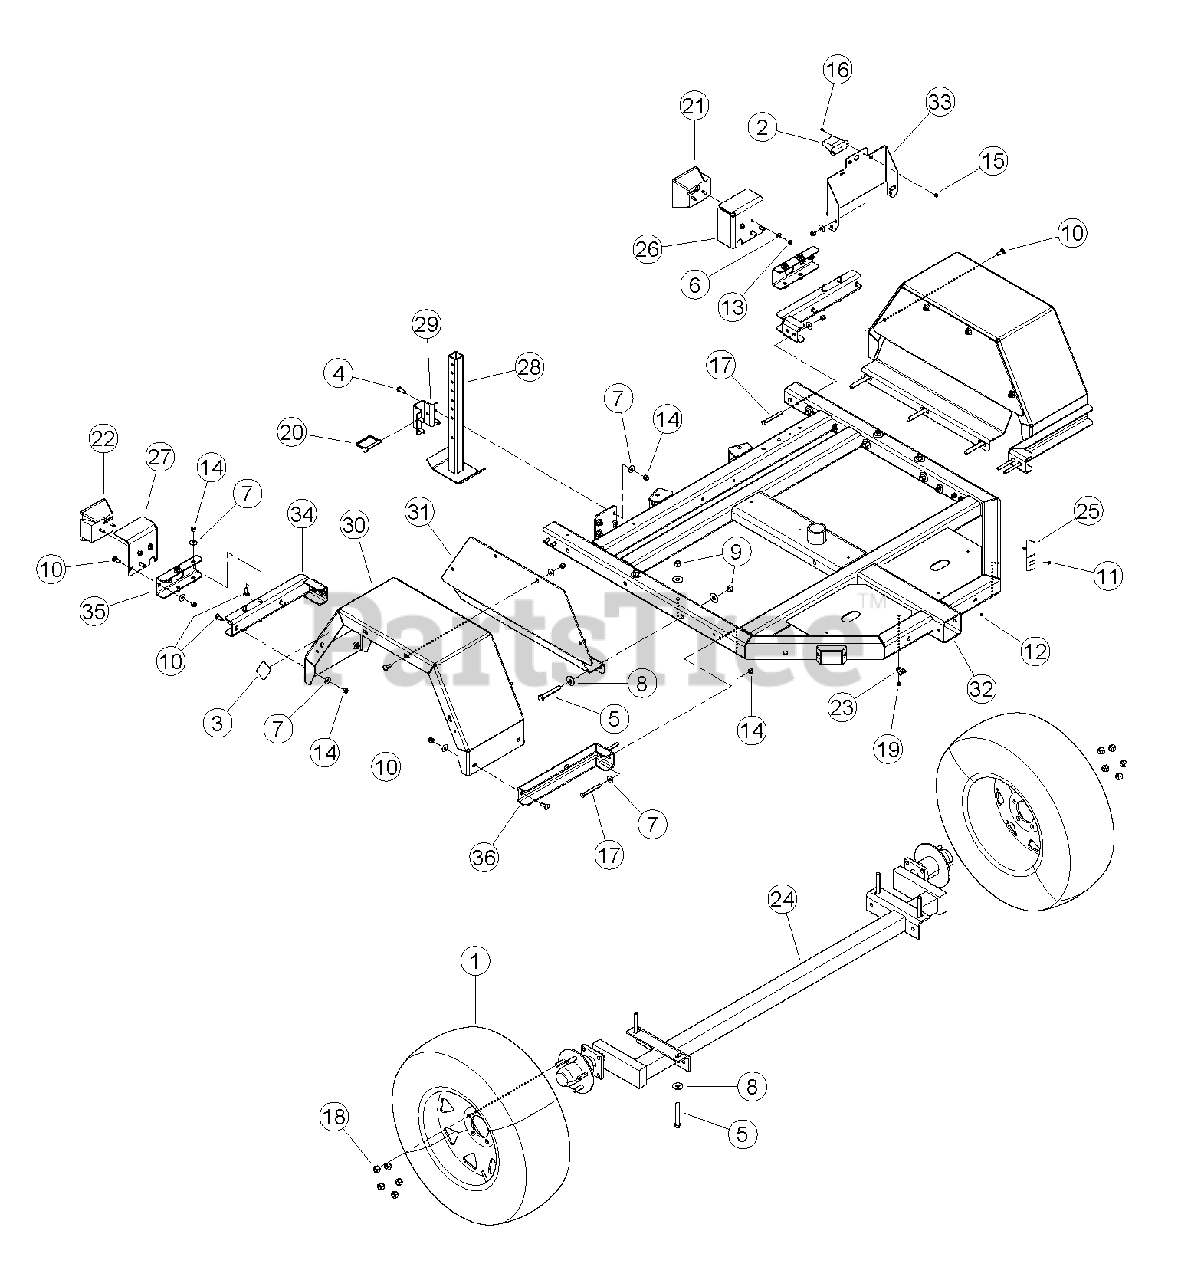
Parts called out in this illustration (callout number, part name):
1	ASSY, 15 INCH TIRE + WHEEL
2	LIGHT, LICENSE PLATE
3	REFLECTOR, WIDE ANGLE RED
4	BOLT, 3/8 X 1 HEX GR5 ZP
5	BOLT, 1/2 X 3-1/2 HEX GR5 ZP
6	WASHER, 1/4 FLAT ZP
7	WASHER, 3/8 FLAT ZP
8	WASHER, 1/2 FLAT ZP
9	NUT, 1/2 CENTERLOCK GRB ZP
10	BOLT, 3/8 X 1 CRG GR5 NC ZP
11	SCREW, #10 X 3/4 HEX TAP SC
12	NUT, 8-32 NYLOCK
13	NUT, 1/4 NE NYLOCK ZP
14	NUT, 3/8 NE NYLOCK ZP
15	NUT, 10/24 NYLOCK TYPE NM ZP
16	MACH. SCREW, 10-24 X 1/2 PAN HD PH ZP
17	BOLT, 3/8 X 3-1/4 HEX GR5 ZP
18	NUT, 1/2-20 WHEEL
19	RIVET, 1/4 X 1/2 AL BLIND DOME HEAD
20	PIN, 3/8" X 2-3/4" SNAP
21	LIGHT, LH TAIL
22	LIGHT, RH TAIL
23	CLAMP, CABLE MOUNT
24	AXLE, TORSION SUSPENSION
25	LIGHT, AMBER SIDE MARKER
26	BRACKET, LH TAILLIGHT
27	BRACKET, RH TAILLIGHT
28	WELDMENT, REAR STABILIZER
29	GUIDE, TRAILER SUPPORT
30	FENDER, CHIPPER
31	BRACKET, FENDER
32	WELDMENT, CHIPPER TRAILER
33	BRACKET, LICENSE PLATE
34	BRACKET, FENDER
35	BRACKET, LIGHT
36	BRACKET, FENDER
